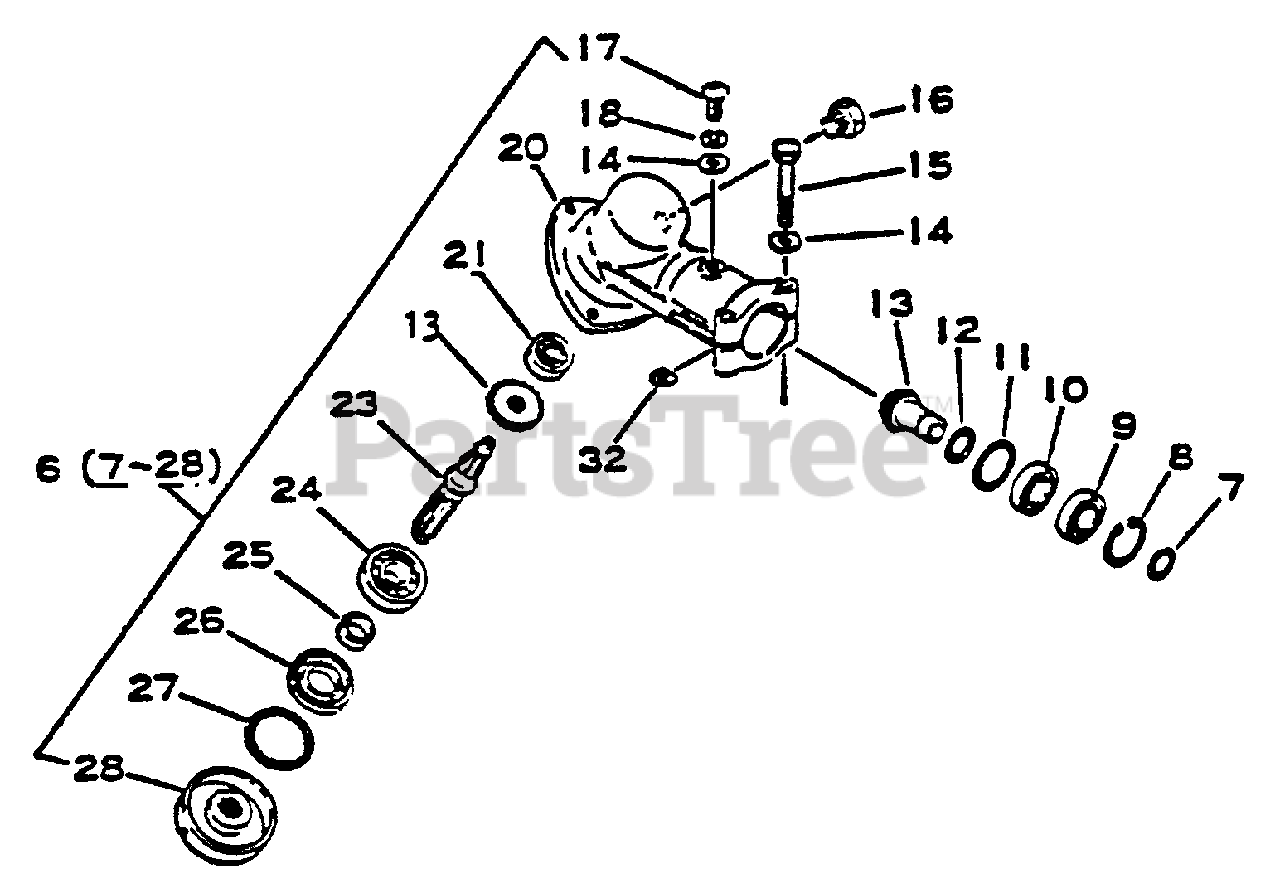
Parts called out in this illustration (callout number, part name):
6	GEAR CASE ASSY
7	RING, RETAINING - 10
8	RING, RETAINING - 22
9	BEARING, BALL - 6900Z
10	BEARING, BALL - 6900
13	GEAR SET
14	WASHER - 5
15	BOLT - 5X35
16	BOLT - 8X8
17	SCREW - 5X10
18	LOCKWASHER - 5
20	CASE, GEAR
21	BEARING, BALL - 626
23	GEAR - SHAFT
24	BEARING, BALL - 6000
26	SEAL, OIL
27	RING, RETAINING - 26
28	ADAPTOR, BLADE - UPPER
